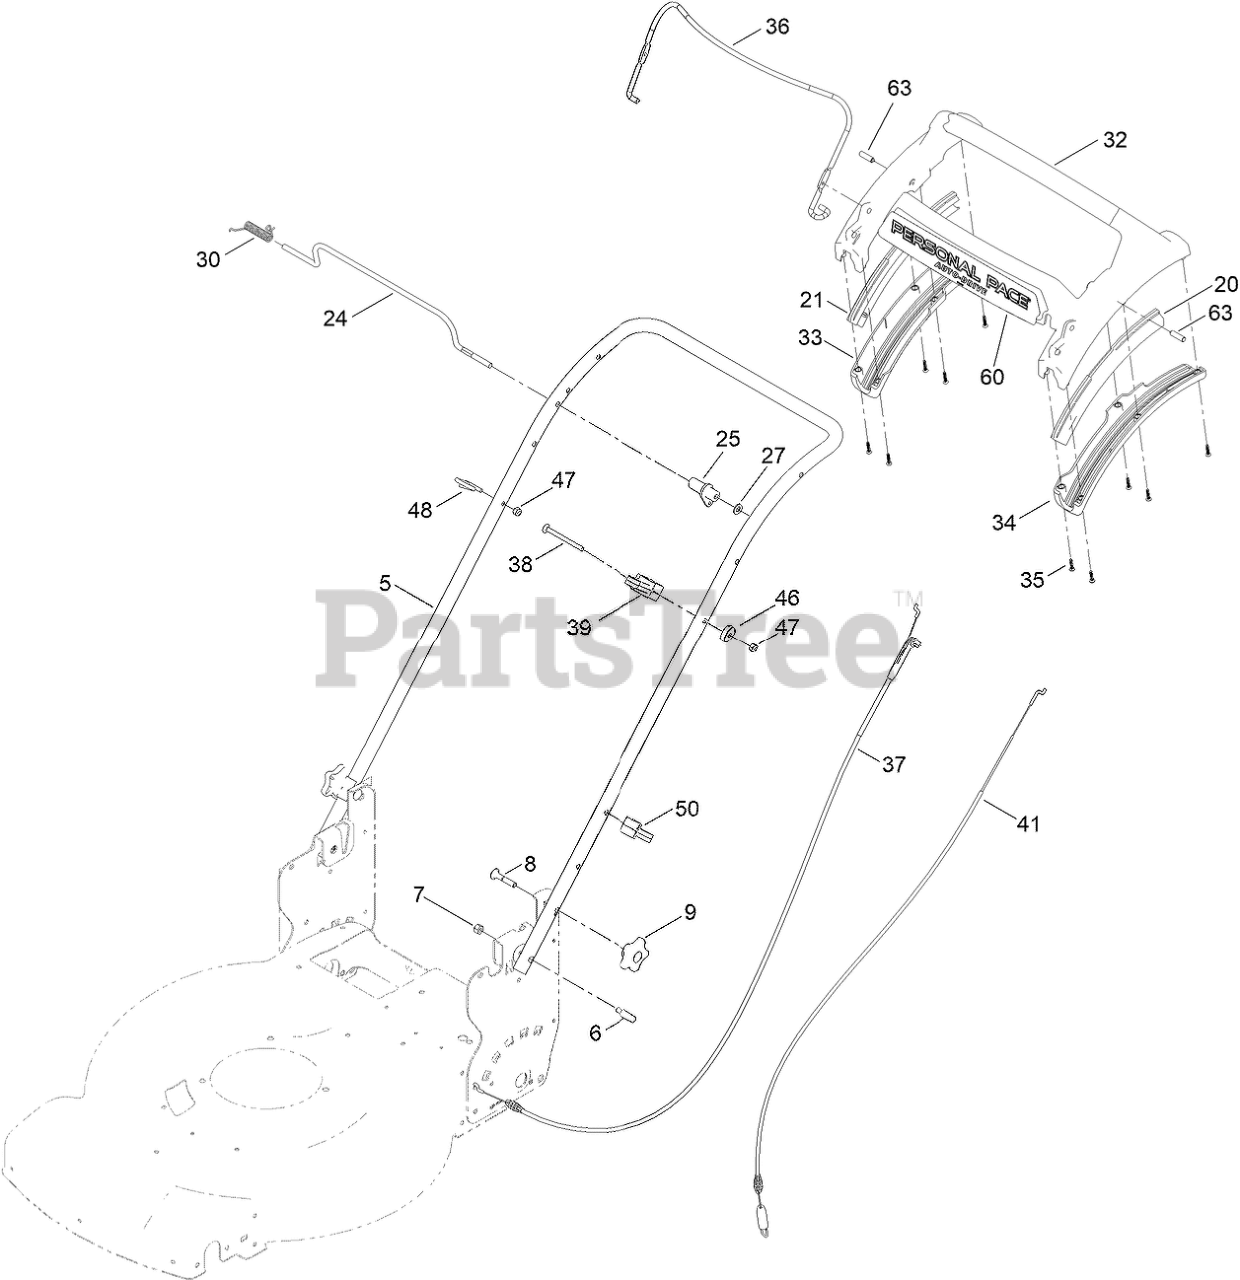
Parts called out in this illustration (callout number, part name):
5	HANDLE-CURVED
6	BOLT-SHOULDER, HANDLE
7	NUT-LOCK, NI
8	SCREW-CARR
9	KNOB-HANDLE
20	GUIDE-CURVED, LH (RWD)
21	GUIDE-CURVED, RH (RWD)
24	ROD-CONTROL, TRACTION
25	LEVER-TRACTION, RWD
27	WASHER-PLAIN
30	SPRING-TORSION
32	HANDLE-PERSONAL PACE, CURVED
33	BOTTOM-HANDLE, RH
34	BOTTOM-HANDLE, LH
35	SCREW-PPH
36	BAIL-BRAKE
37	CABLE-BRAKE, PP BS
38	SCREW-CARR
39	ANCHOR-CABLE, RWD
41	CABLE-TRACTION, RWD (PP)
46	WASHER-CURVED
47	NUT-LOCK, NI
48	GUIDE-ROPE
50	GUIDE-CABLE
63	PIN-HANDLE, PP
